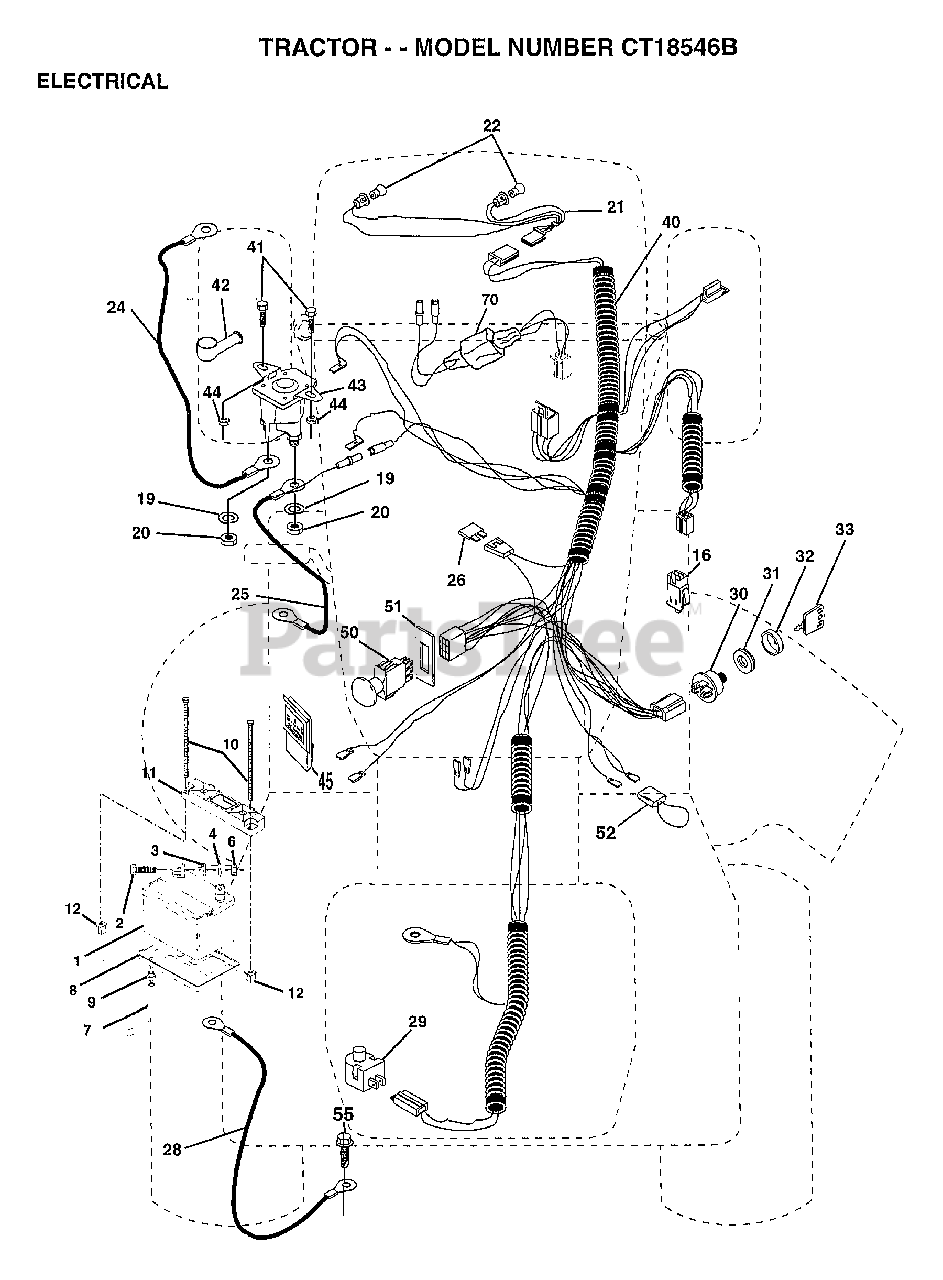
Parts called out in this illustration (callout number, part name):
2	BOLT LT
3	WASHER
4	LOCKWASHER
7	"DRAIN TU T, BATT"
8	"TRAY T, BATTERY"
9	HOSE CLAMP T
11	HOLDDOWN BATTERY
16	SWITCH INTERLOCK
20	NUT
21	"HARNESS,LIGHT SOC"
22	HEADLAMP BULB
24	"CABLE T, BATTERY"
25	CABLE.6GA.22W/16W
26	FUSE HYT
28	CABLE.GRND.6GA.21
29	SWITCH SEAT
30	SWITCH IGN 4POS
31	NUT IGNITION
32	COVER KEY SWITCH
33	KEY
40	HARNESS IGNITION
41	BOLT HXHD FIN
44	NUT HXKEP 1/4X20
50	PTO SWITCH.BLK
51	RING RETAIN PTO
52	PROTECTION LOOP
55	SCREW LT
70	HARN.ENG.TRI-CKT
